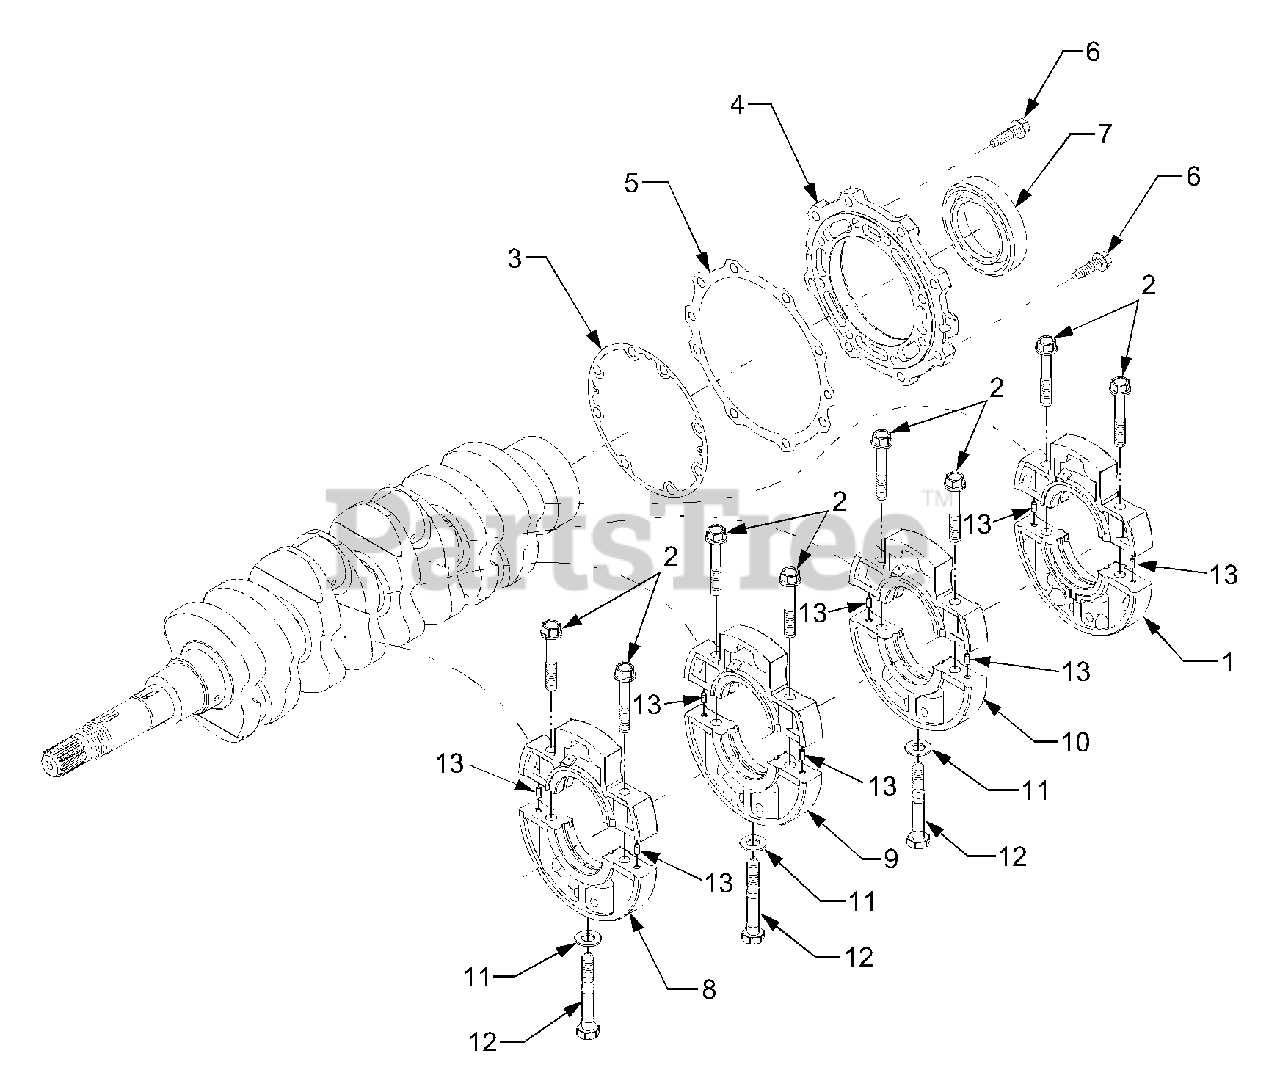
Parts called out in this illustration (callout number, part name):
1	Main Bearing Case Ass'y
2	Bolt 1, Bearing Case
3	Gasket, Bearing Case
4	Cover, Main Bearing Case
5	Gasket, Bearing Case
6	Pin, Flange Bolt
8	Main Bearing Case 1 Ass'y
9	Main Bearing Case 2 Ass'y
10	Main Bearing Case 3 Ass'y
12	Bolt 2, Bearing Case
13	Pin, Straight
